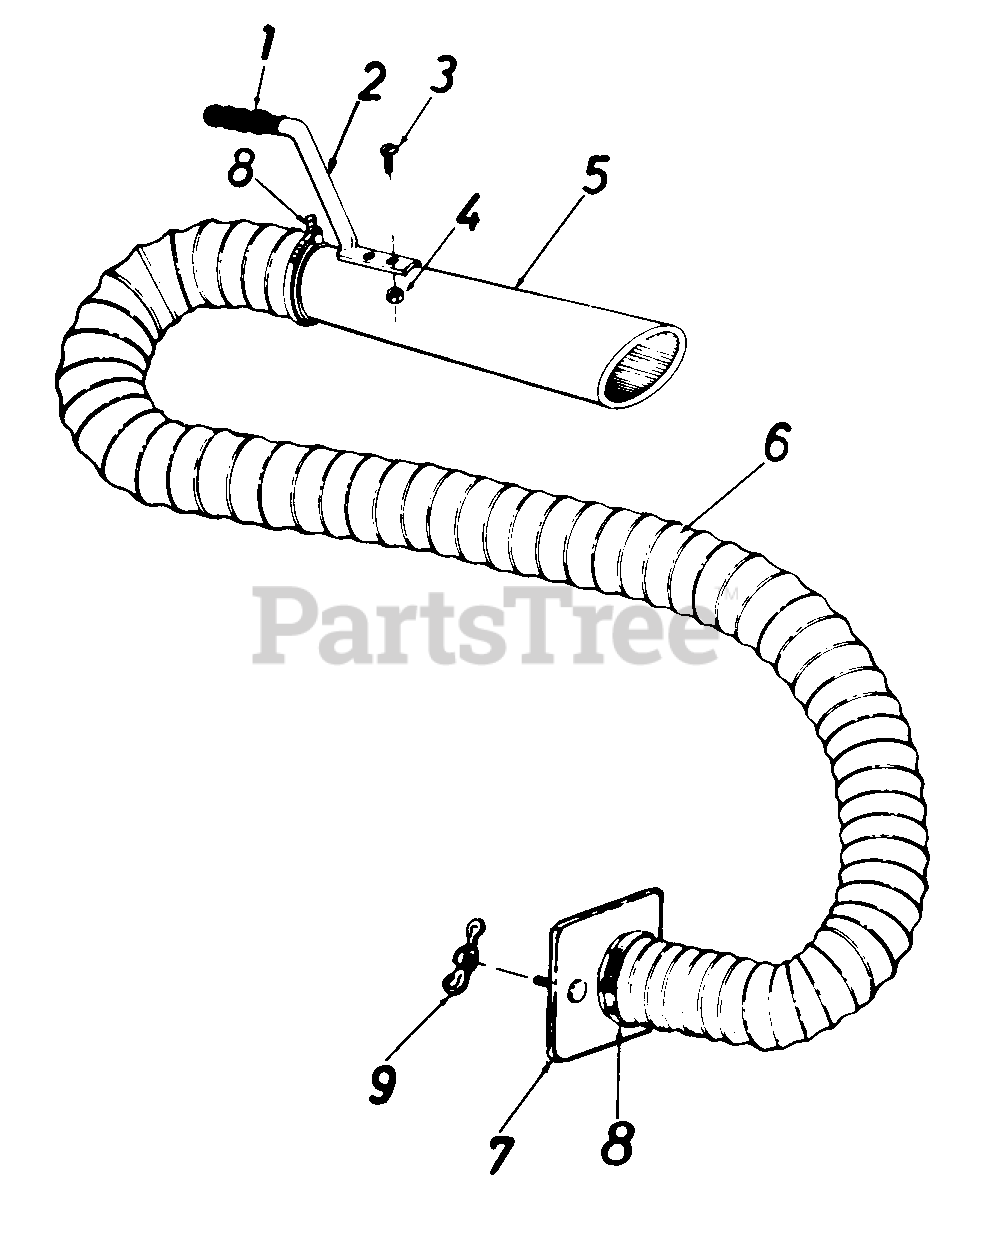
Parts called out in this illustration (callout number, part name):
1	Handle Grip
2	Handle
3	TrussSemsScr. 10-24x 1/2" Lg.
4	Hex Nut 10-24 Thd.
5	Hose Nozzle
6	Flexible Hose 4" Dia. x 10' Lg.
7	Hose Adapter Plate
8	Hose Clamp-For 4" Dia. Hose
9	Wing Nut 1/4-20Thd.
